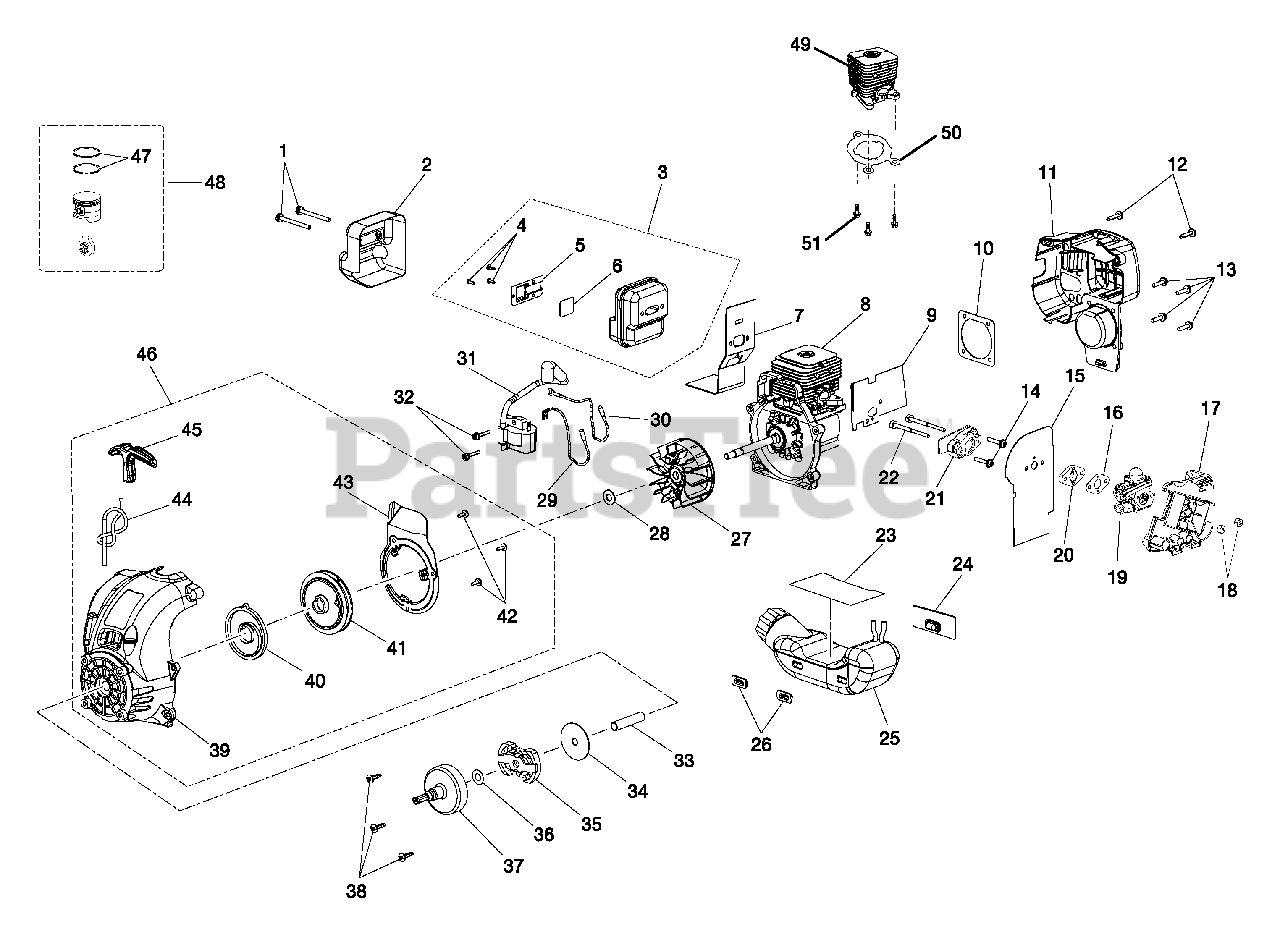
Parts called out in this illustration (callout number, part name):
1	SCREW (10-24 X 2-1/8 in. TORX TR. HD. )
2	HEAT SHIELD
3	MUFFLER ASSEMBLY
4	SCREW (RECESSED PAN HD.)
5	OUTLET TUBE
6	SCREEN
7	MUFFLER GASKET
8	SHORT BLOCK ASSEMBLY (30 cc) (EXTERNAL GASKETS NOT INCLUDED)
9	INTAKE GASKET
10	COVER GASKET
11	REAR HOUSING
12	SCREW (10-14 X 7/8 in. TRUSS HD. T.F.)
13	SCREW W/LOCK WASHER (10-24 X 3/4 in. PAN HD. TORX)
14	SCREW (PAN HD.)
15	CARBURETOR GASKET
16	CARBURETOR GASKET (NON-STRATO)
17	AIR FILTER BASE
18	LOCK NUT (10-24)
19	CARBURETOR ASSEMBLY
20	SPACER
22	CARBURETOR MOUNTING BOLT (#10 X 2-1/2 in.)
23	TANK INSULATION GASKET
24	RUBBER BUMPER
25	FUEL TANK ASSEMBLY W/CAP
26	BUMPER
27	ROTOR W/PAWLS ASSEMBLY
28	WASHER
29	LEAD W/TERMINALS
30	LEAD W/TERMINALS
31	IGNITION MODULE W/3 SEC. KILL SWITCH
32	SCREW (THD FORMING)
33	SPACER TUBE
34	WASHER (PKG)
35	CLUTCH ASSEMBLY
36	CLUTCH WASHER
37	DRUM AND CONNECTOR
38	SCREW (10-24 X 3/4 in.)
39	STARTER HOUSING AND EYELET ASSEMBLY
40	SPRING AND CONTAINER
41	STARTER PULLEY ASSEMBLY
42	SCREW (THREAD FORMING)
43	BAFFLE/ISOLATOR
44	STARTER ROPE 42 (PKG)
45	STARTER GRIP
46	STARTER HOUSING ASSEMBLY
47	PISTON RING
48	PISTON W/ROD ASSEMBLY
49	CYLINDER, 30CC
50	CYLINDER GASKET
51	SCREW (M5 X 20 MM )
